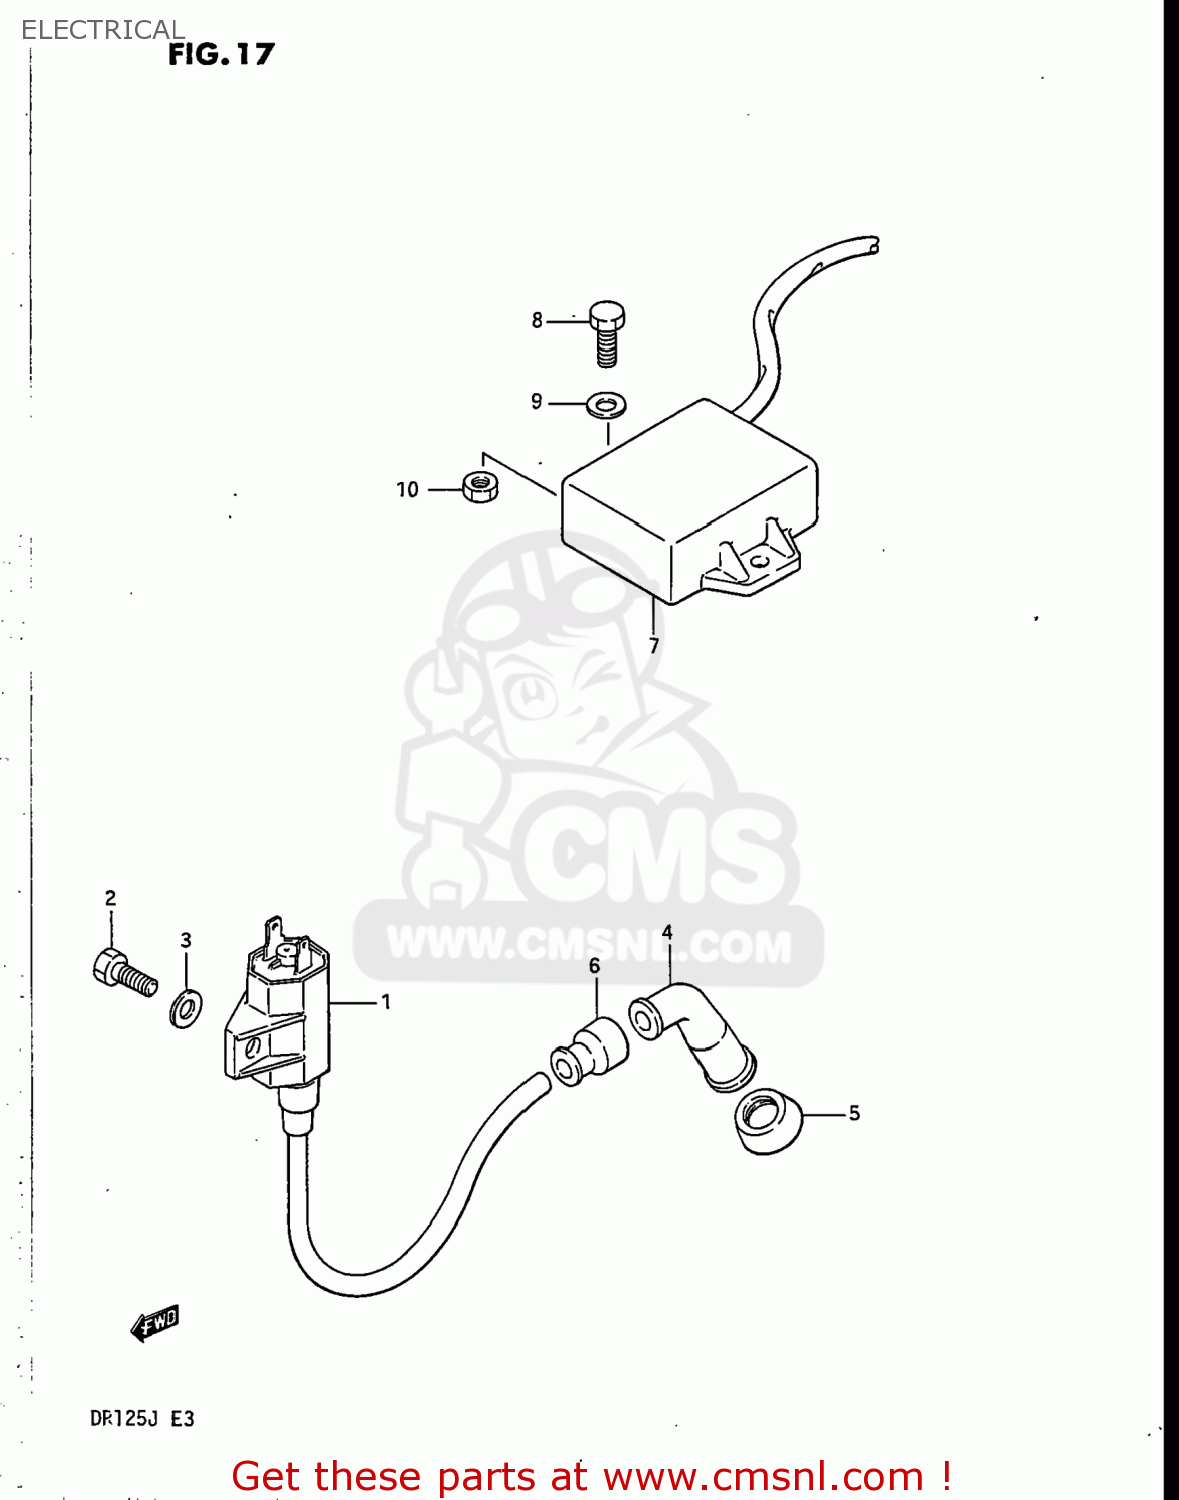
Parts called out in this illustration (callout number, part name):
1	COIL ASSEMBLY,IGNITION
2	BOLT
3	WASHER, LOWER
4	CAP,SPARK PLUG
5	SEAL,SPARK PLUG CAP
6	SEAL,SPARK PLU
7	CDI UNIT
8	BOLT
9	WASHER, LOWER
10	NUT
